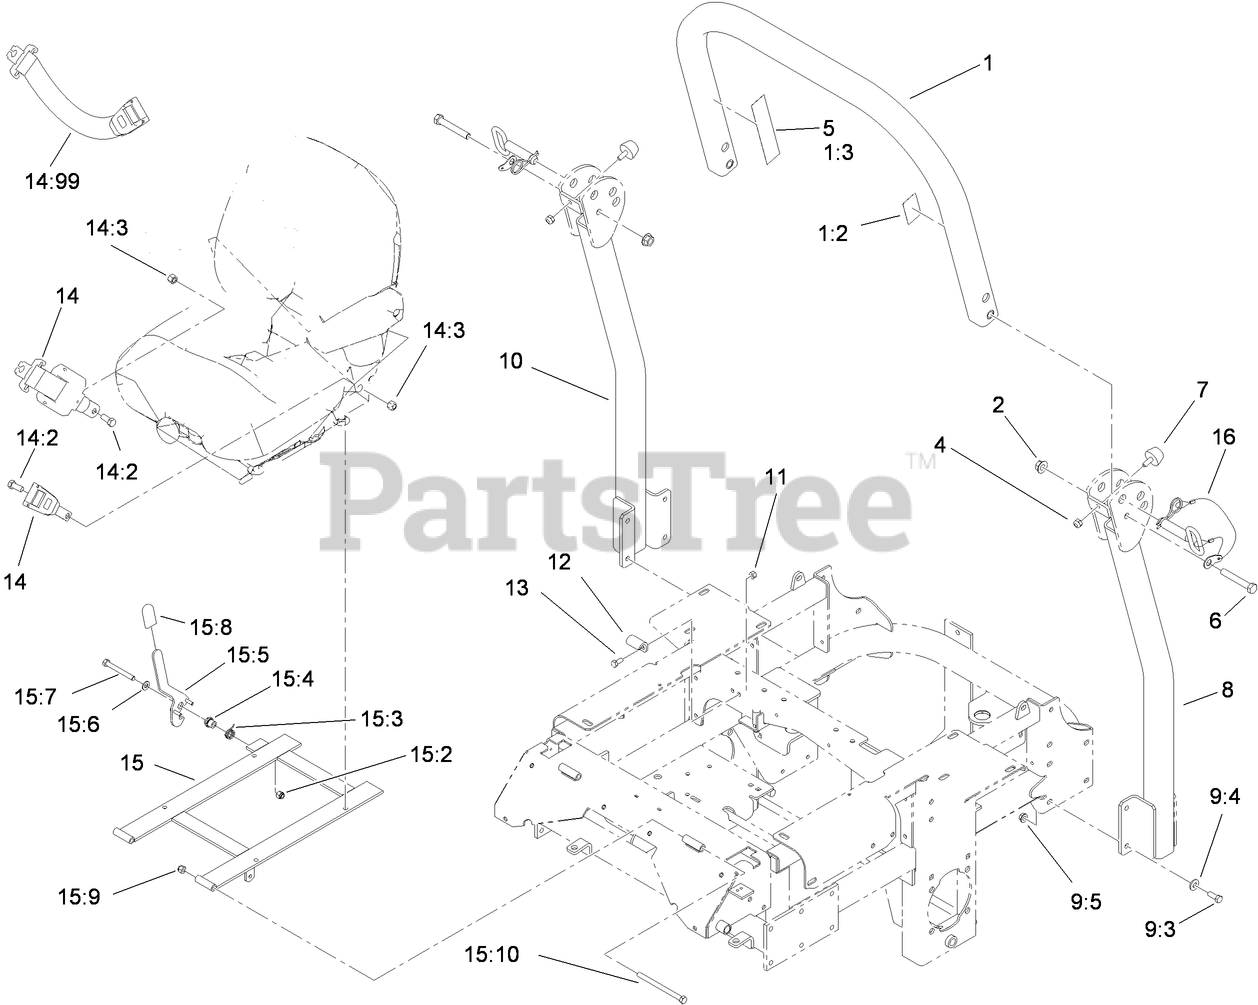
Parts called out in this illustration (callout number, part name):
1	Upper Tube ASM
1:2	DECAL-ROPS
1:3	DECAL-WARNING, FOLDING ROPS
2	NUT-HF
4	NUT-LOCK, NI
5	DECAL-WARNING
6	SCREW-HH
7	BUMPER-RUBBER
8	TUBE-SUPPORT, LH
9	BAG-BOLT, ROPS
9:3	SCREW-HH
9:4	WASHER-BELLEVILLE
9:5	NUT-HHF, WHIZ
10	TUBE-SUPPORT, RH
11	NUT-LOCK, NI
12	Catch-Latch, Seat
13	SCREW-HH
14	RETRACTABLE SEATBELT KIT
14:2	SCREW-HH
14:3	NUT-LOCK
14:99	SEAT BELT EXTENSION KIT
15	SEATFRAME ASM
15:2	NUT-LOCK, NI
15:3	SPRING-TORSION
15:4	BUSHING-LATCH, SEAT
15:5	LATCH ASM
15:6	WASHER-FLAT
15:7	SCREW-HH
15:8	GRIP-LEVER
15:9	NUT-LOCK, NI
15:10	SCREW-HH
16	PIN-FOLD, ROPS
